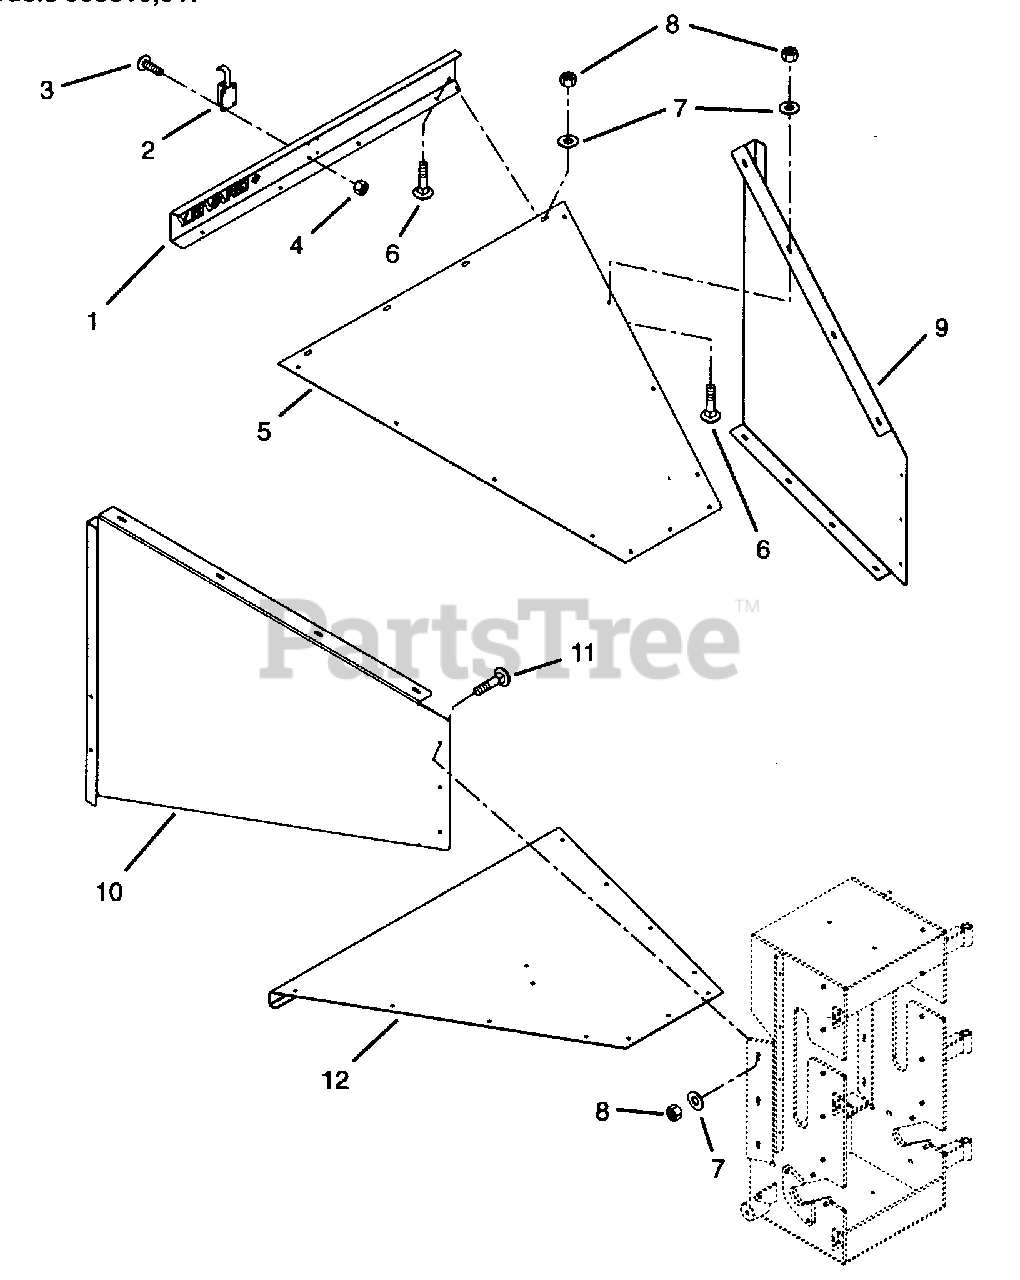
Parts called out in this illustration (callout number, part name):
1	Hopper Safety Tab
2	Latch - 495
3	Screw-Machine 10-24 x .50
4	Nut-Keps 10-24
5	Hopper Top
6	Bolt-Round Head Square Neck .31-18 x .75
7	Washer-Flat-Steel .38 x .875 x .083
8	Nut-Locking .375-16
9	Hopper Left Hand Side
10	Hopper Right Hand Side
11	Bolt-Round Head Square Neck .312-18 x 1.00
12	Hopper Bottom
